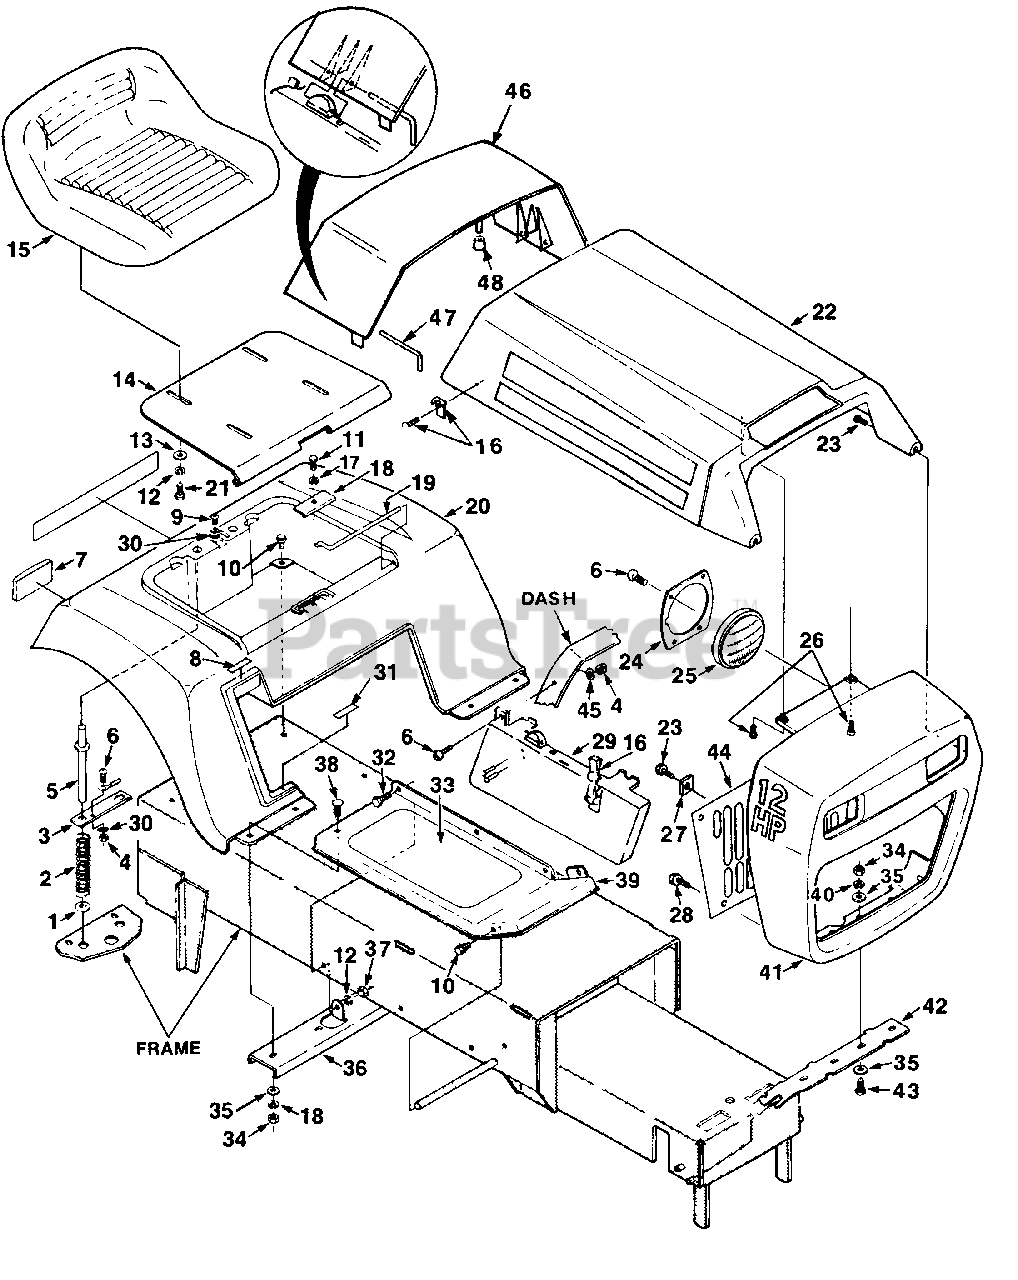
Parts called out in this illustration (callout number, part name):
1	WASHER- Insulation
2	SPRING- Compression
3	CONTACT- Interlock
4	NUT- Hex 10-24
5	PIN- Seat support
6	SCREW- 10-24 X 3/8
7	REFLECTOR- Reflex
8	DECAL- Hi-lift
9	SCREW- Phillips 10-1/2
10	BOLT- 1/4-14 X .44
11	SCREW- Cap 1/4-20 X 3/4
12	WASHER- Lock 5/16
13	WASHER- 5/16
14	PAN- Seat
15	SEAT- Jacobsen
17	WASHER- Lock 1/4
18	BRACKET- Hitch
19	ROD- Hinge
21	SCREW- Hex hd. 5/16-18 X 5/8
24	RETAINER- Light
25	LIGHT- Head
26	SCREW- Tap hex hd. 4 1/4 - 14 X 3/4
28	SCREW 1/4-14 X 1/2
29	PANEL- Side R.H.
30	WASHER- Lock #10
31	DECAL- Lo-lift
32	SCREW- Cap 5/16-18 X 1
33	PAD- Footboard
34	NUT- Hex 1/4-20
35	WASHER- Plain 1/4
36	BRACKET- Footboard
37	NUT- Hex 5/16-18
38	BOLT- 1/4-20 X 1
39	FOOTBOARD, RH
40	WASHER- Lock 1/4
42	HINGE- Grille
43	SCREW- 1/4-20 X 7/8
44	GRILLE SCREEN
46	PANEL- Hood
47	PIN- Attachment
48	BUMPER- Rubber
